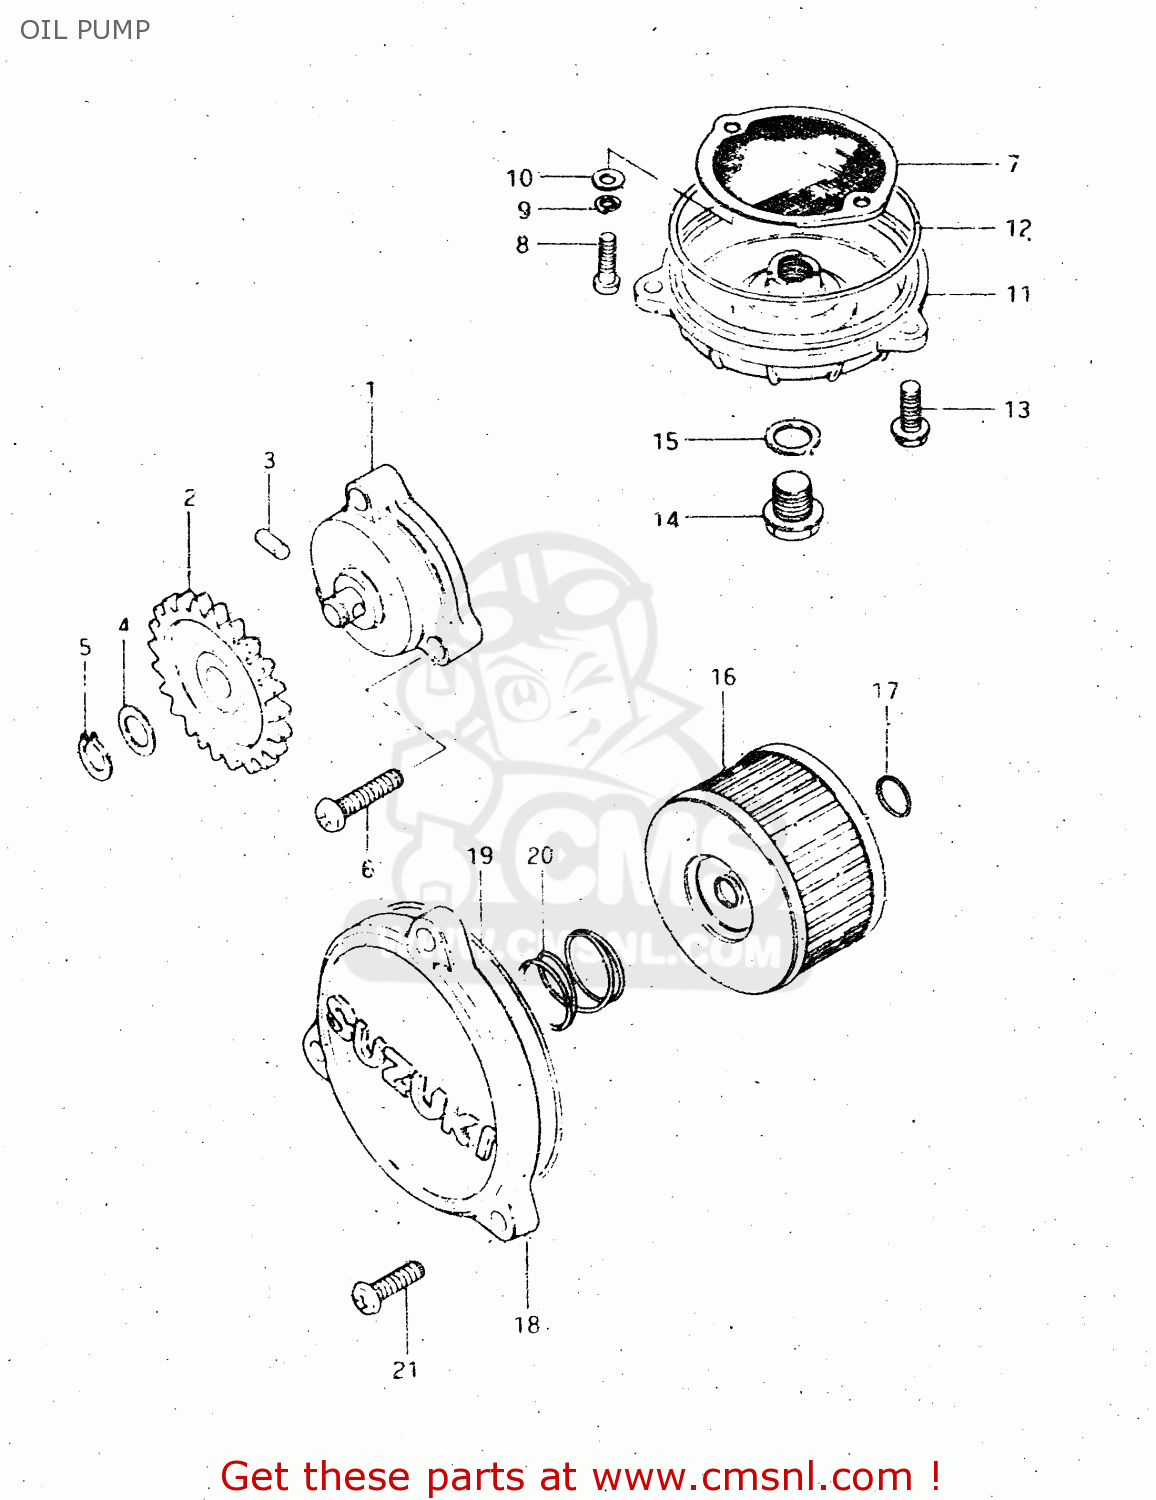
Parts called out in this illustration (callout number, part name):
1	PUMP ASSY,ENGINE OIL
2	GEAR,OIL PUMP DRIVEN
3	PIN(4X15.8)
4	SHIM
5	CIRCLIP
6	SCREW
7	STRAINER,ENGINE OIL
8	SCREW
9	LOCK WASHER
10	WASHER
11	CAP,OIL STRAINER
12	O RING(D:2.4,ID:85)
13	BOLT,REAR
14	PLUG
15	GASKET(14X19.2X2) (NAS)
16	FILTER,ENGINE OIL
17	O RING(D:2.4,ID:15.8)
18	CAP,ENGINE OIL FILTER
19	O RING(D:2.4,ID:73)
20	SPRING
21	SCREW
